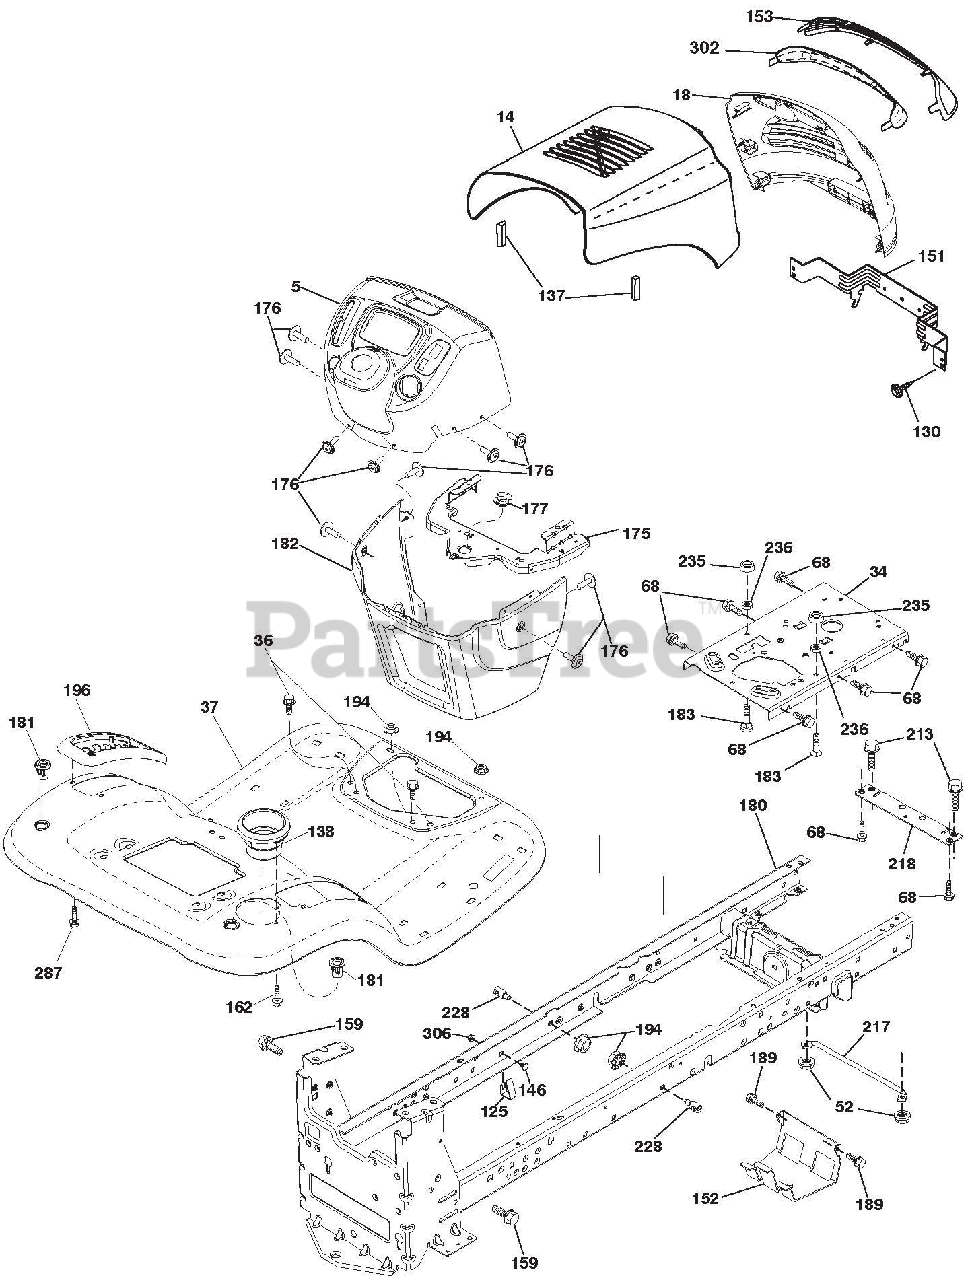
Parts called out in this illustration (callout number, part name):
34	PLATE.ENGINE.WELDED.CHASSIS
36	SCREW.5/16-18X3/4.SMGML.TAP/R
37	FENDER TLT W/CPH W/FW 422
52	Nut, Hex, Crownlock 5/16-18
68	SCREW.THDROL.5/16-18 X 1/2TYTT
125	CLIP.FUEL.LINE
137	BUMPER.HOOD.LARGE. 1.75"
138	CUPHOLDER TL TEX 428
151	Bracket Pivot
152	SHIELD.BROWNING.W/TEX
153	LENS.GRILLE.BAR
159	SCREW.HEXWSH THDR3/8-16X3/4.BL
162	SCREW.HEX.WSH.HI-LO.1/4X1/2UNC
175	CROSSMEMBER.LT
176	SCREW.#10-24X5/8.RND.QUDRX.GIM
177	BUSHING.STEERING.LT
180	CHASS WLDMT TL 12 GA/2PC 18/22
181	BUSHING MNT FEND CRGO BLK TEX
182	DASH LOWER.LT.CCS
183	BOLT.FIN.HEX.5/16-18 UNC X1-1/
189	SCREW.5/16-18X3/4.SMGML.TAP/BL
191	INSERT REFLECTIVE RH
194	Nut, Lock Hex Flange 5/16-18 u
196	CONSOLE ASSEMBLY
213	Bolt, Hex Head 5/16-18 x 3/4
217	ROD.PIVOT.HOOD
218	X-PIECE.HOOD.STOP.NON/STEALTH
225	BUMPER
228	STUD.FASTNER.W/'D'ANTI-ROTATIO
235	SPACER.FENDER
236	NUT.CENTER LOCK.5/16-18 UNC
287	SCREW.HEX.WASHEAD.1/4-20 X 3/8
302	Insert Lens Reflect
306	Nut, Hex, Flangelock 3/8-16
